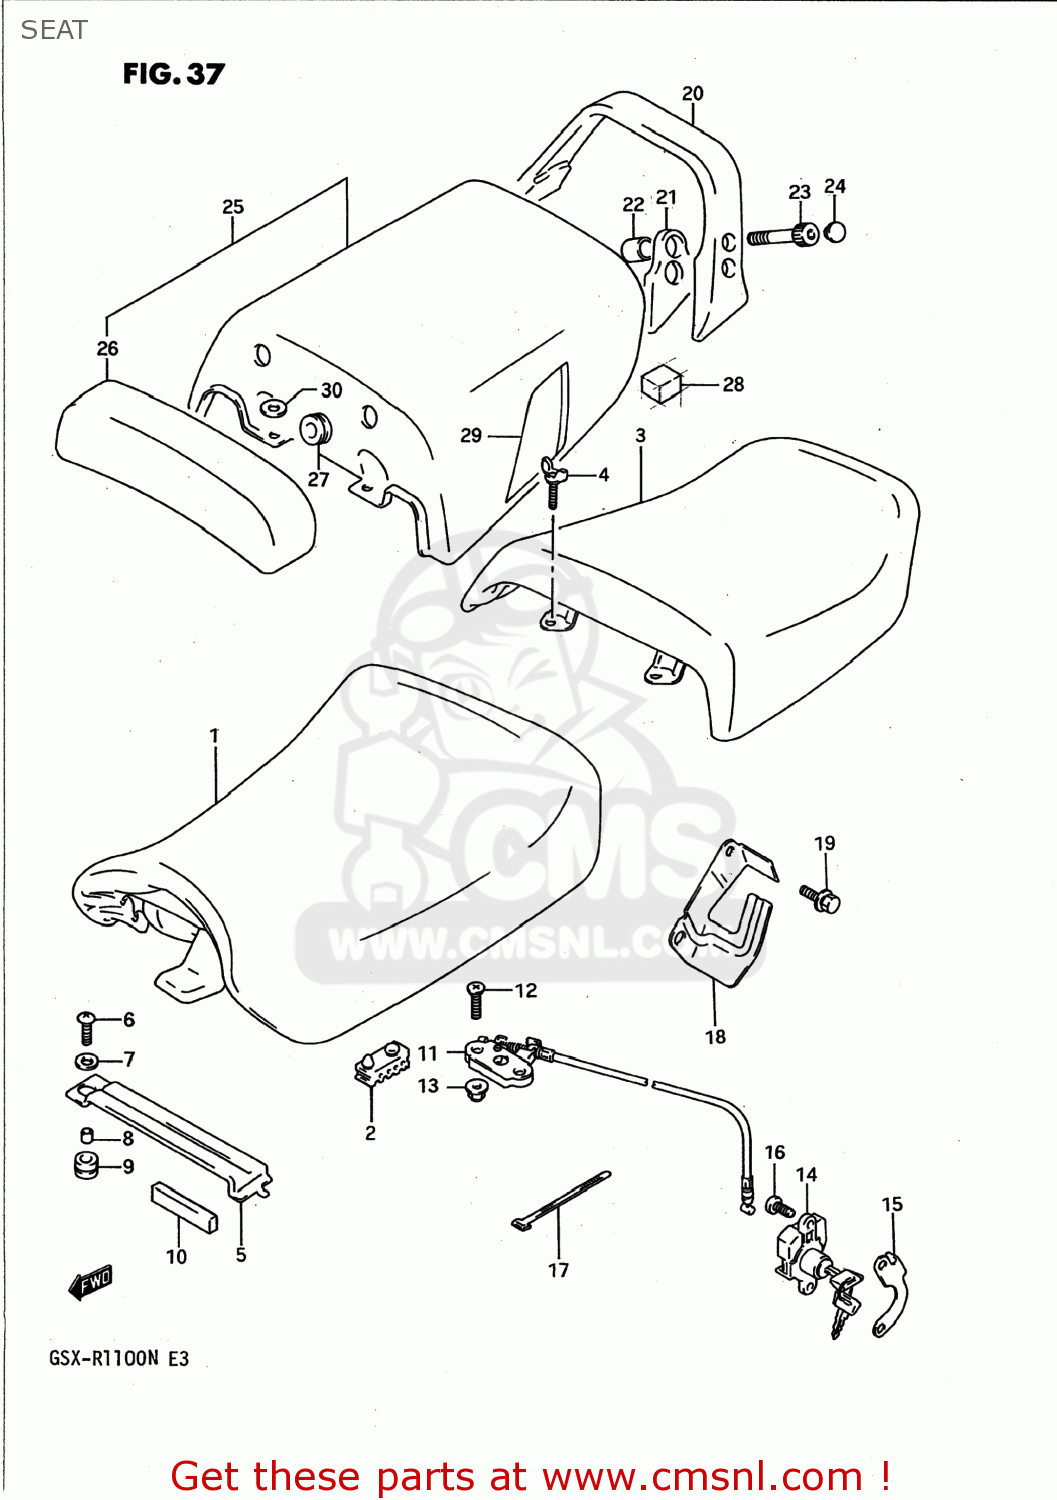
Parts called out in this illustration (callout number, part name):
1	SEAT ASSY
2	CUSHION,SEAT(40X20X15)
3	SEAT ASSEMBLY,PILLION
4	SCREW(6X20)
5	PLATE,SEAT SUPPORT,REAR
6	SCREW, CENTER
7	WASHER
8	SPACER (6.1X8X9.5)
9	CUSHION
10	CUSHION,PLATE SEAT SUPPORT
11	BRACKET,SEAT SUPPORT RR
12	SCREW
13	NUT
14	LOCK SET,SEAT
15	PLATE,SEAT LOCK
16	SCREW(6X12)
17	CLAMP
18	PLATE,SEAT LOCK CABLE
19	BOLT
20	HANDLE,PILLION RIDER
21	CUSHION,PILLION RIDER
22	SPACER
23	BOLT
24	CAP(OD:14.5)
25	BOX SET,SEAT TAIL
26	BACKREST,SEAT(BLACK)
27	CUSHION
28	MUD GUARD,REAR FENDER
29	TAPE SET,SEAT TAIL BOX
30	WASHER
